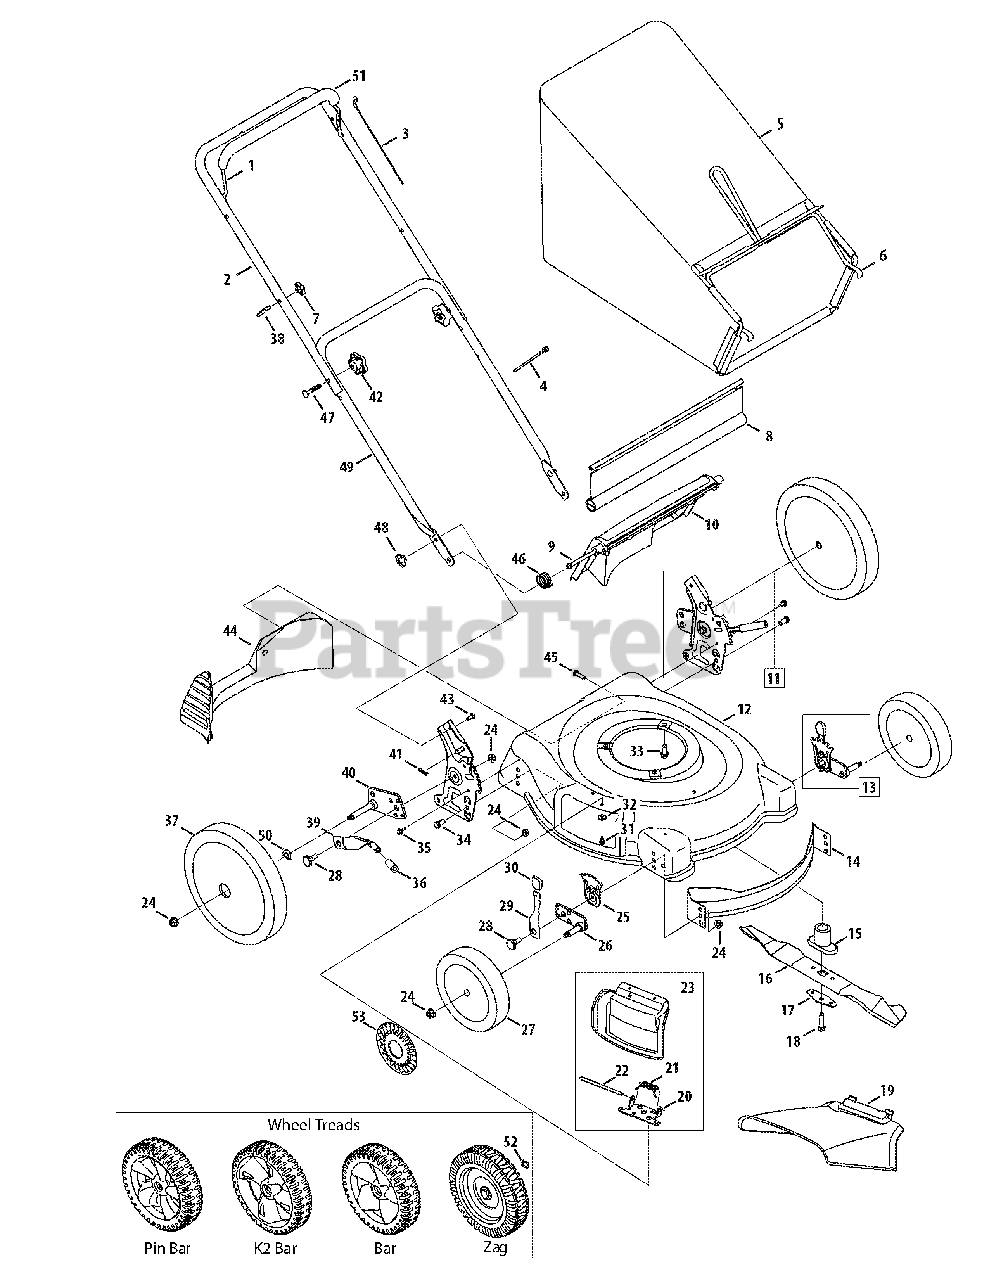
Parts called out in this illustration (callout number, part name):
1	Blade Control
2	Upper Handle
3	Control Cable, 37.25"
3	Control Cable, 40"
4	Cable Tie
5	Grass Bag Assembly
7	Handle Knob
8	Trailshield
9	Pivot Rod
10	Rear Discharge Door
11	Rear Handle Bracket Assy. - LH
11	Rear Handle Bracket Assy. - RH
12	Deck 21-inch - Red, MTD
12	Deck 21-inch - Black Jack
12	Deck 21-inch - Silver Flake
13	Front Hgt. Adj. Assy., 8" Whl. - LH
13	Front Hgt. Adj. Assy., 8" Whl. - RH
13	Front Hgt. Adj. Assy., 7" Whl. - LH
13	Front Hgt. Adj. Assy., 7" Whl. - RH
14	Front Baffle
15	Blade Adapter w/Star
15	Blade Adapter - 25mm
16	21-inch Mulching Blade
17	Bell Blade Support
18	Hex Screw, 3/8-24 x 2.5
19	Side Discharge Chute
20	Deflector Chute Adaptor
21	Torsion Spring
22	Hinge Pin
23	Mulch Plug Assembly
24	Flange Lock Nut 3/8-16
25	Height Adjustment Plate
26	Pivot Arm Assy LH (7" wheel)
26	Pivot Arm Assy RH (7" wheel)
26	Pivot Arm Assy RH (8" wheel)
26	Pivot Arm Assy LH (8" wheel)
27	Front Wheel, 8 x 1.8, K2 Bar
27	Front Wheel, 7 x 1.8, Bar
27	Front Wheel, 8 x 2.125, Zag, Yellow
28	Shoulder Scr., .5D x .385
29	Front Spring Lever
30	Height Adjust Knob
31	TT Screw, 1/4-20 x .500
32	Bell Washer
33	TT Screw, 3/8-16 x 1.0
34	Hex Screw, 3/8-16 x .75
35	TT Screw, 1/4-20 x .625
36	Foam Grip
37	Rear Wheel, 12 x 1.8, K2 Bar
37	Rear Wheel, 12 x 2.125, Zag
38	Eye Bolt
39	Rear Hi-Wheel Spring Lever
40	Rear Pivot Arm Assy - RH
40	Rear Pivot Arm Assy - LH
41	Hairpin Clip
42	Star Knob
43	Carriage Bolt ,1/4-20 x .75
44	Rear Baffle
45	Screw HL, 1/4-15 x 1.00
46	Torsion Spring - RH
47	Carriage Bolt, 5/16-18 x 2
48	Wing Nut
49	Lower Handle
50	Spring Washer
51	Deluxe Bail Cover
51	Deluxe Bail Cover - Red
51	Deluxe Bail Cover - Gray
51	Deluxe Bail Cover - Yellow
52	Wave Washer, .510 x .750 x .017
53	Hub Cap
53	Hub Cap - Yellow
